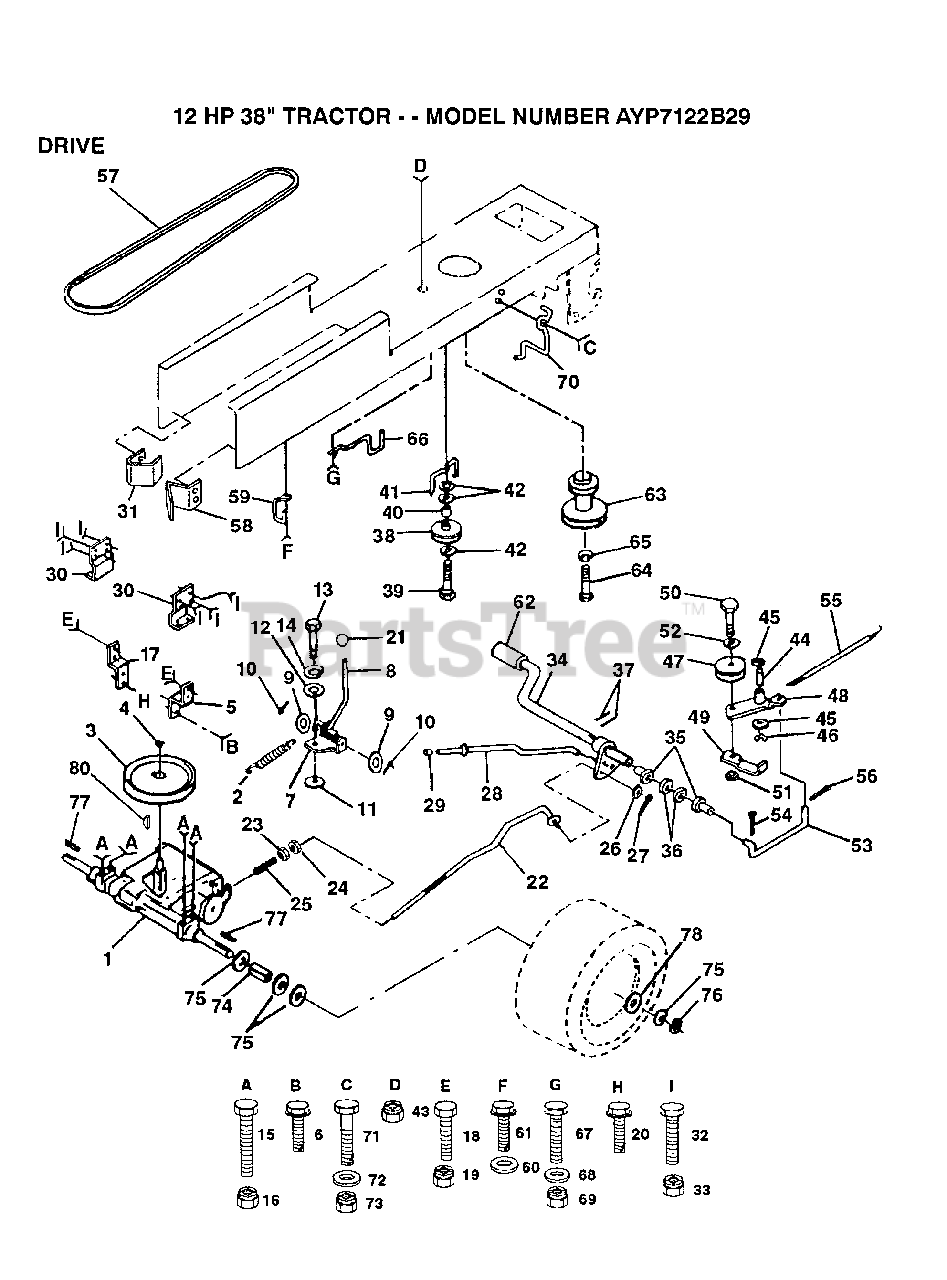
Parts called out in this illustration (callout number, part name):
3	PULLEY TRANS
5	STRAP TORQUE
6	SCREW
7	PLATE SHIFT LT
8	SHIFTER ROD
9	WASHER
10	PIN COTTER 1/8
11	WASH-SHFT PLT LT
12	WASHER LT
14	LOCKWASHER
15	BOLT HEX
17	STRAP TORQUE
20	SCREW
21	KNOB T (1/2-HOLE)
23	NUT
24	NUT
25	SPRING ROD LT
26	WASHER
27	COTTER PIN
28	PARKING BRAKE ROD
29	PLUNGER CAP T
30	BRACKET LT
31	"KEEPER,BELT LH T"
35	NYLON BEARING
36	WASHER LT
38	PULLEY.IDLER.FLAT
39	BOLT
40	SPACER T
41	BELT KEEPER LT
42	WASHER
44	"LY, BEARING"
45	WASHER LT
46	KLIP RING
48	ARM IDLER
49	RETAIN BELT
52	WASHER
53	"LINK, CLUTCH T"
54	COTTER PIN
55	"SPRING, RETURN LT"
56	COTTER PIN
57	BELT-V.90.0.GD.DR
58	"KEEPER,BELT RH T"
60	WASHER
61	SCREW
62	PEDAL COVER T
64	BOLT
65	LOCKWASHER
66	KEEPER.BELT.ENG.L
67	BOLT
68	WASHER
70	KEEPER BELT ENG
71	BOLT
72	WASHER
75	WASHER
76	E-RING LT
77	SQUARE KEY
78	WASHER
79	WASHER
